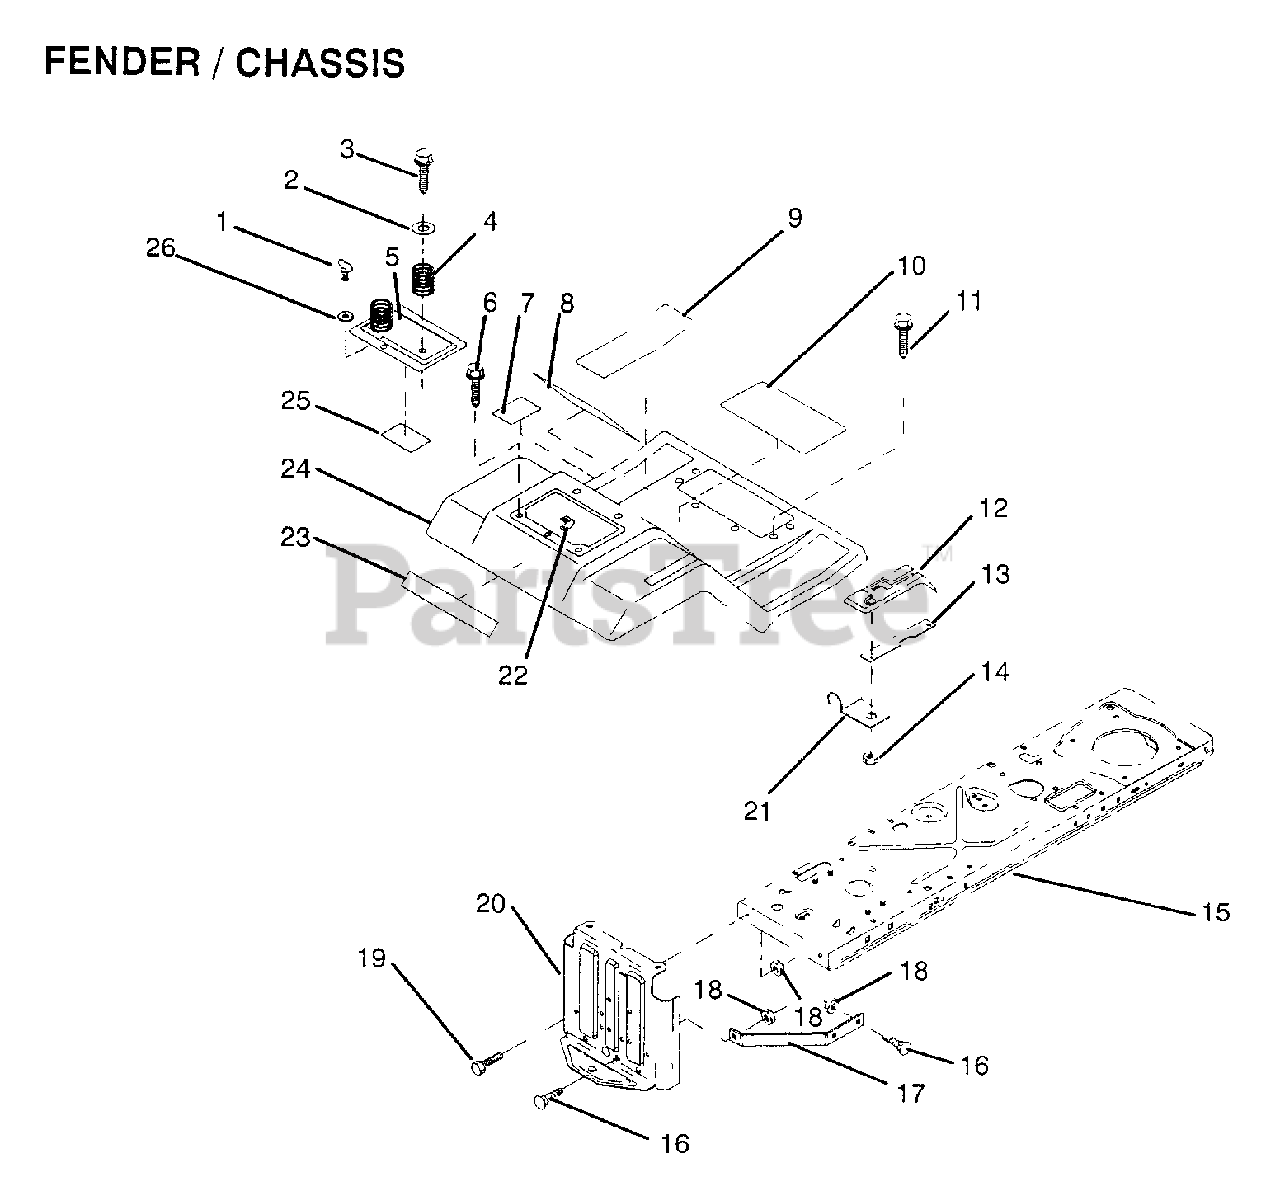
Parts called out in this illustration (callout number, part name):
1	STUD.1/4.TURN
2	WASHER
3	SCREW
4	SPRING COMPRESSIO
6	SCREW LT
7	DECAL DRIVE
8	DECAL
10	DECAL
11	SCREW
12	CONSOLE SHFT 4SP
14	NUT
15	FRAME ASS'Y
16	BOLT
17	"BRACE,DRAWBAR "
19	BOLT
20	DRAWBAR
21	"CLIP,INSULATOR"
22	RECEPTACLE LT
23	DECAL, FENDER
24	"FENDER,FOOTREST T"
25	DECAL
26	RETAINER LT
